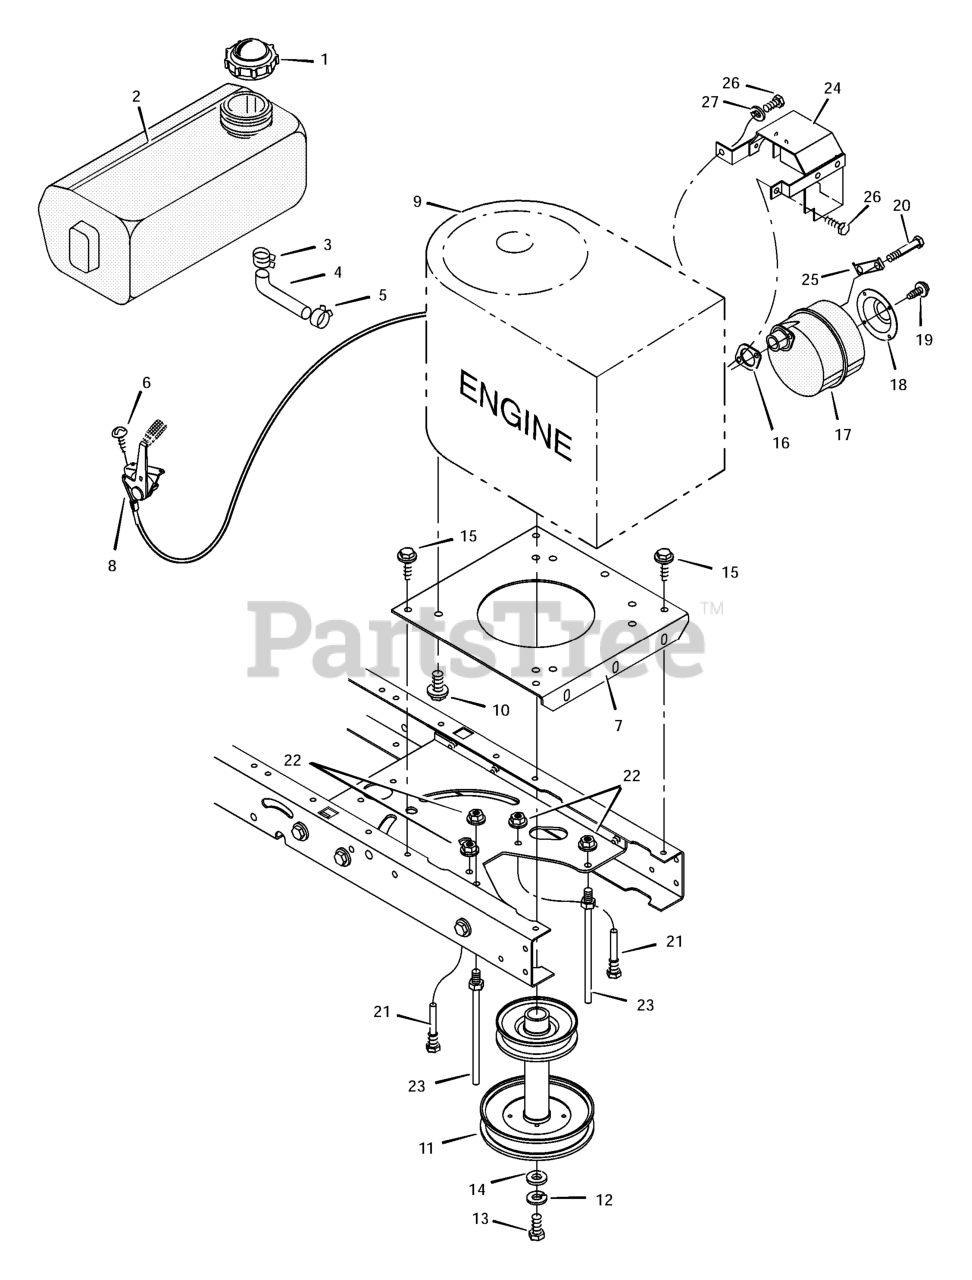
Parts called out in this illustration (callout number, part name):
1	Fuel Cap
2	Fuel Tank
3	Hose Clamp
4	Fuel Line
5	Hose Clamp
7	Plate, Engine
8	Throttle Control
9	Engine *
10	Bolt, Engine Mount
11	STACK PULLEY ASSEMBLY
12	Lockwasher
13	Bolt, Hex
16	GASKET, Exhaust
17	Muffler
18	Deflector, Muffler
20	Bolt, Hex
21	Guide, Belt
22	Nut, Flange
23	Guide, Belt
24	Shield, Heat
25	Lock, Screw
